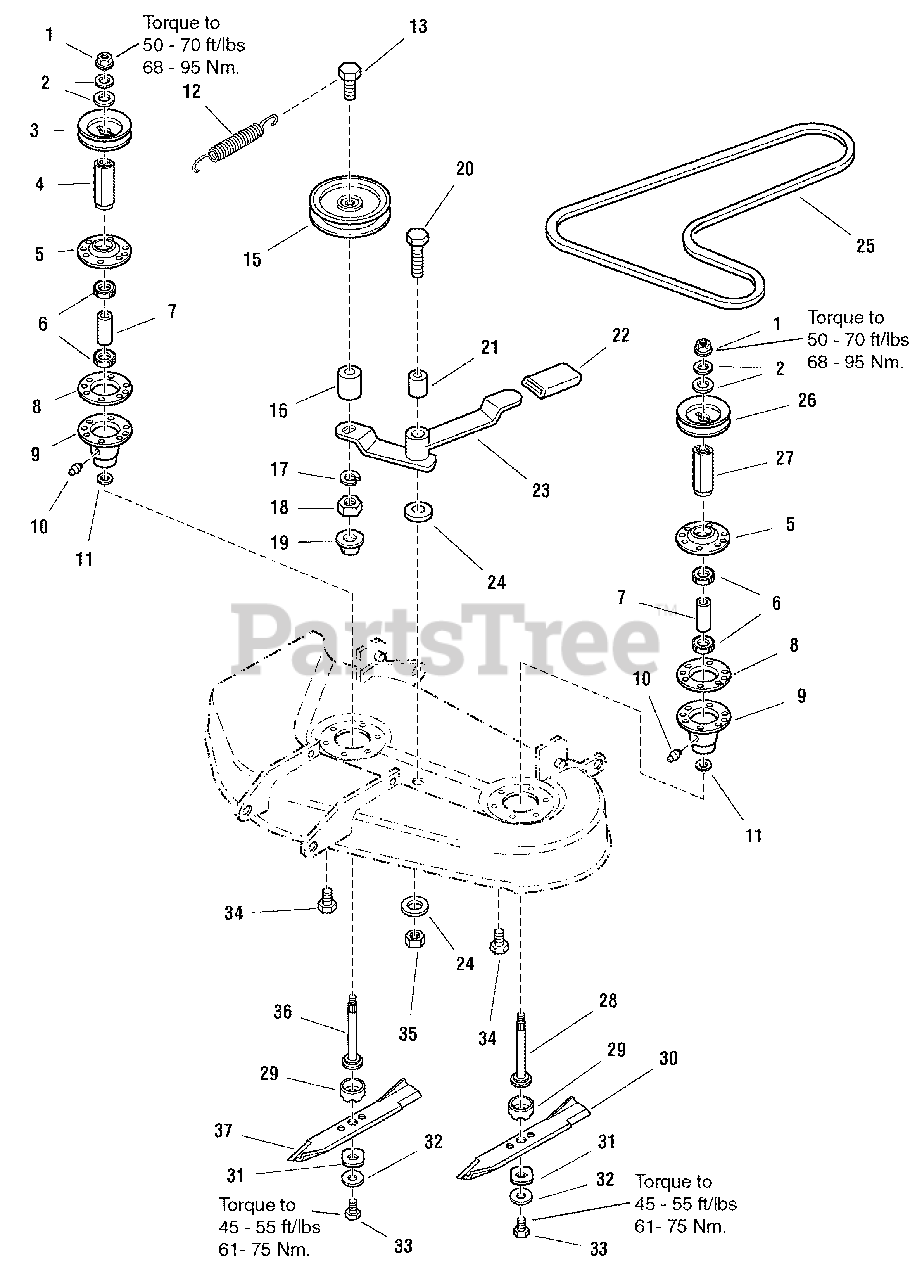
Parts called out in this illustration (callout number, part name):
1	NUT, Hex, Flange, 9/16-18
2	WASHER, Belleville
4	HUB, Pulley, 1-35/64"
5	COVER, Arbor Housing ASSEMBLY
8	GASKET, Foam
9	HOUSING ASSEMBLY, Arbor Bottom, w/Lube Fitting
10	FITTING, Grease
13	CAPSCREW, 3/8-16 x 2-1/2
15	PULLEY, Idler, Backside
17	LOCKWASHER, 3/8
18	NUT, Hex, 3/8-16
19	NUT, Hex, Flange, Lock, 3/8-16
20	CAPSCREW, Hex Head, 3/8-16 x 2-3/4
22	GRIP, Lever
23	LEVER ASSEMBLY
24	WASHER, Flat, 3/8
26	PULLEY, 3-3/4"
27	HUB, Pulley, 1-3/16"
28	SHAFT, Arbor, 5-53/64"
29	SHIELD, Grass, Lower
30	BLADE, 14-27/64"
31	WASHER, Hex
32	WASHER, Spring
33	CAPSCREW, Hex Head, 7/16-14 x 1-1/4, GR 8
34	CAPSCREW Taptite, 5/16-18 x 3/4
35	NUT, Hex, 3/8-16
36	SHAFT, Arbor, 6-33/64"
37	BLADE, 19-29/32"
